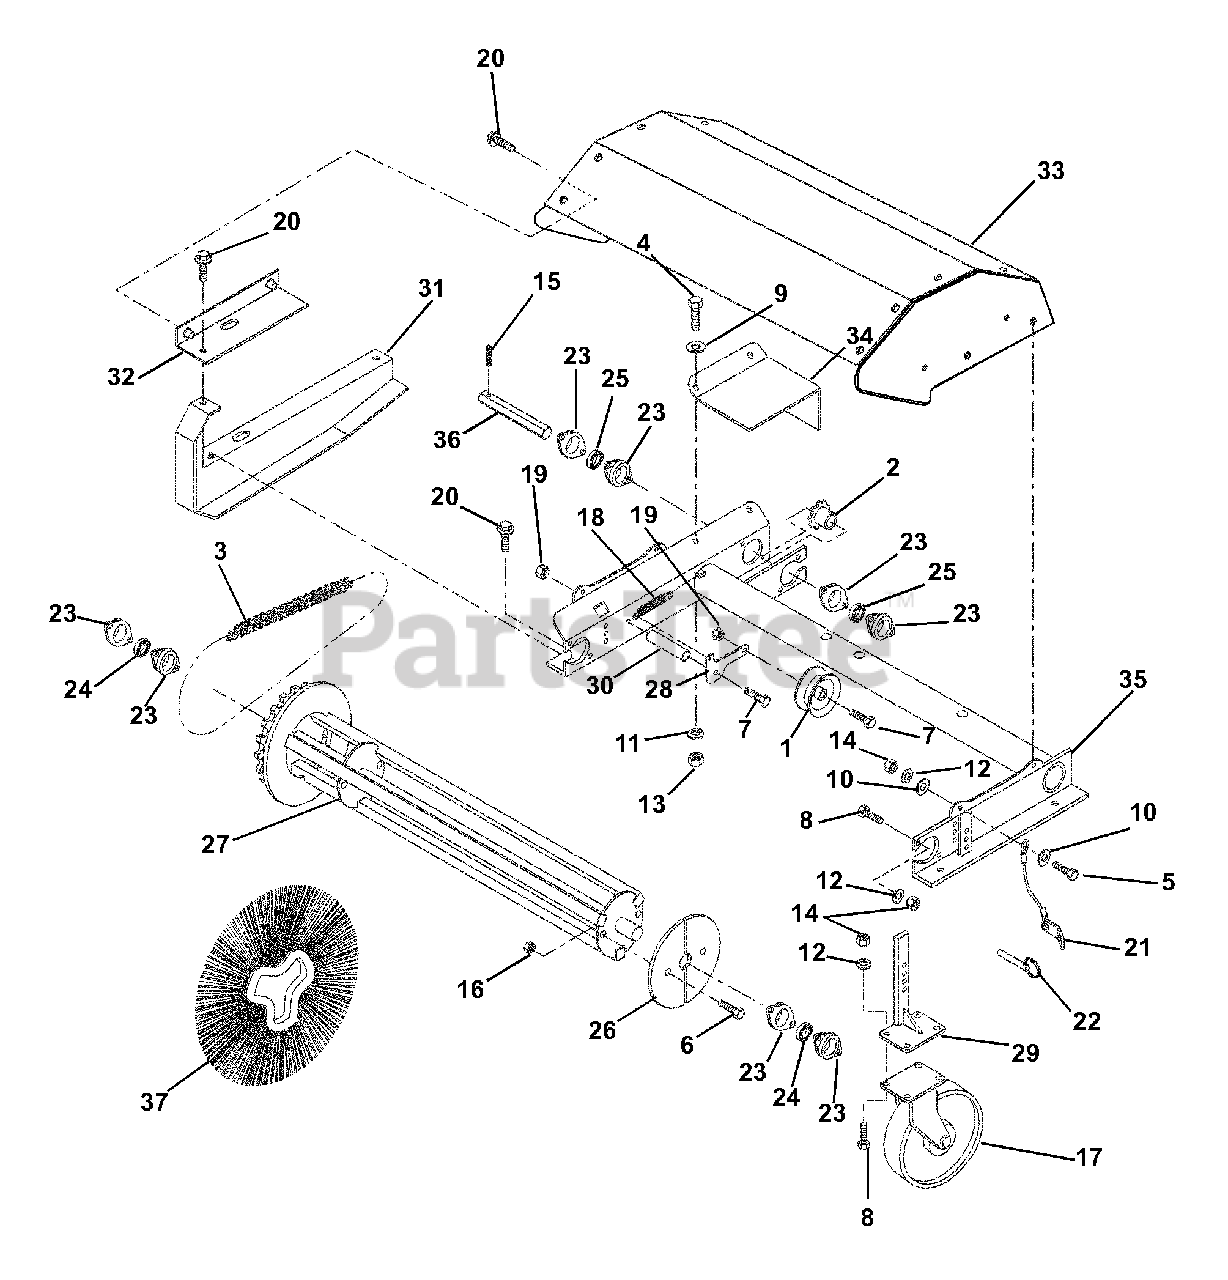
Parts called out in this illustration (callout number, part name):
1	CHAIN TIGHTENER
2	SPROCKET
3	CHAIN, ASS'Y #40X106 EDLS W/LK
4	@BLT-HEX .25-20X.75 GR5 YWZC
5	@BLT-HEX .31-18X1.00 GR5 YWZC
6	@BLT-HEX .31-18X2.25 GR5 YWZC
7	@BLT-HEX .38-16X1.50 GR5 YWZC
8	@BLT-HEX .31-18X.75 GR5 YWZC
9	@WSHR-FL-STL.281X.62X.065 YWZC
10	@WSHR-FL-STL.312X.734X.065 YWZ
11	@WSHR-LK .25X.062 REG YWZC
12	@WSHR-LK .31X.078 REG YWZC
13	@NUT-HEX .25-20 YWZC
14	@NUT-HEX .31-18 YWZC
15	PIN, SPRING LOK .187 X 1.25
16	NUT, LOK STAMPED .312-18 TINN.
17	WHL, 5 DIA.
18	SPRING, TENSION .50 X 3.0
19	@NUT-LK-CTR .38-16 YWZC
20	SCREW, GR 10.9 M6X1-20
21	LANYARD,.06 CAB.1.25X6,TYP C
22	PIN, HITCH, .38 X 2
23	FLANGE, SPHERICAL 2"
24	BRG 1.00 BORE, SPHER. OD.
25	BRG-BALL .884HEXX52MMX1.07
26	RETAINER PLATE (SET OF 2)
27	WELD, CORE C36TW
28	ARM, IDLER,BRM C36TW
29	WELD, CASTER LEG, C36TW
30	BSHG, .62X12 GA X.75
31	SHIELD,CHAIN, ARIENS
32	SHIELD, CHAIN,TOP,ARIENS
33	KIT, HD, ARIENS
34	SHIELD, INPUT, ARIENS
35	WELD, BFRM,ARIENS
36	SHAFT, HEX 20.1", W/HOLE
37	SET,SECTION,24",P,CONV.
